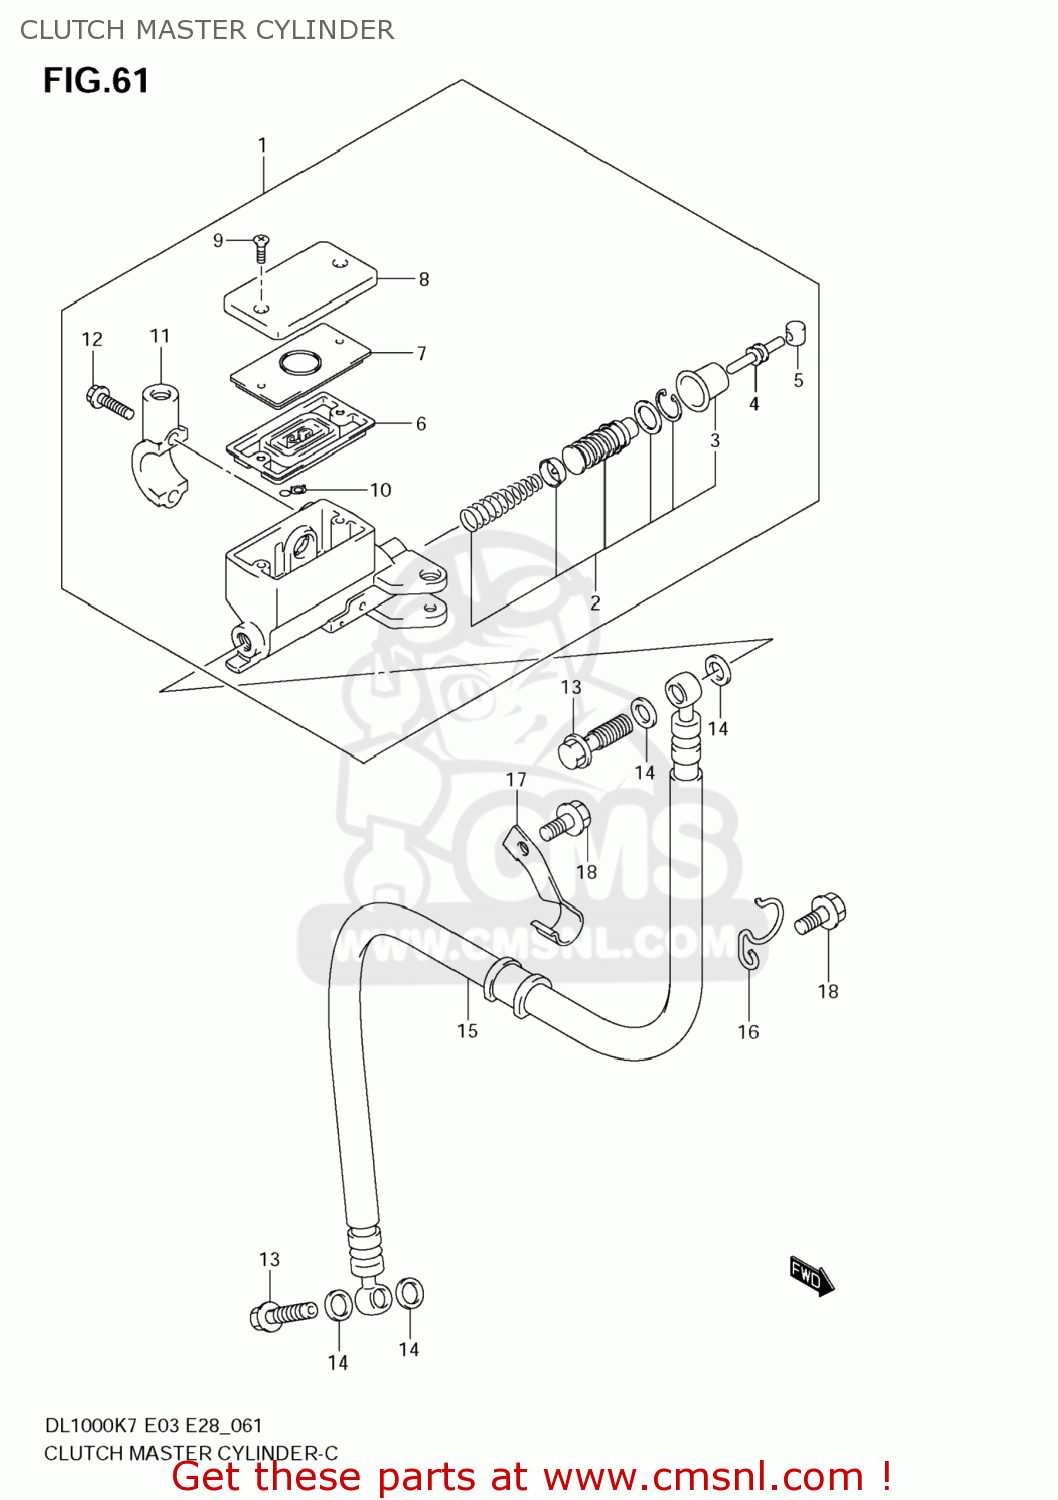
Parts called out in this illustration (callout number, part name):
1	CYLINDER ASSY,
2	PISTON & CUP SET
3	BOOT
4	PUSH ROD
5	BUSH
6	7
7	PLATE,DIAPHRAGM
8	CAP
9	SCREW
10	PROTECTOR
11	HOLDER
12	BOLT(6X22)
13	BOLT UNION
14	WASHER(10X15X1.5)
15	HOSE,CLUTCH
16	CLAMP,CLUTCH HOSE NO.1
17	CLAMP,CLUTCH HOSE NO.2
18	BOLT
